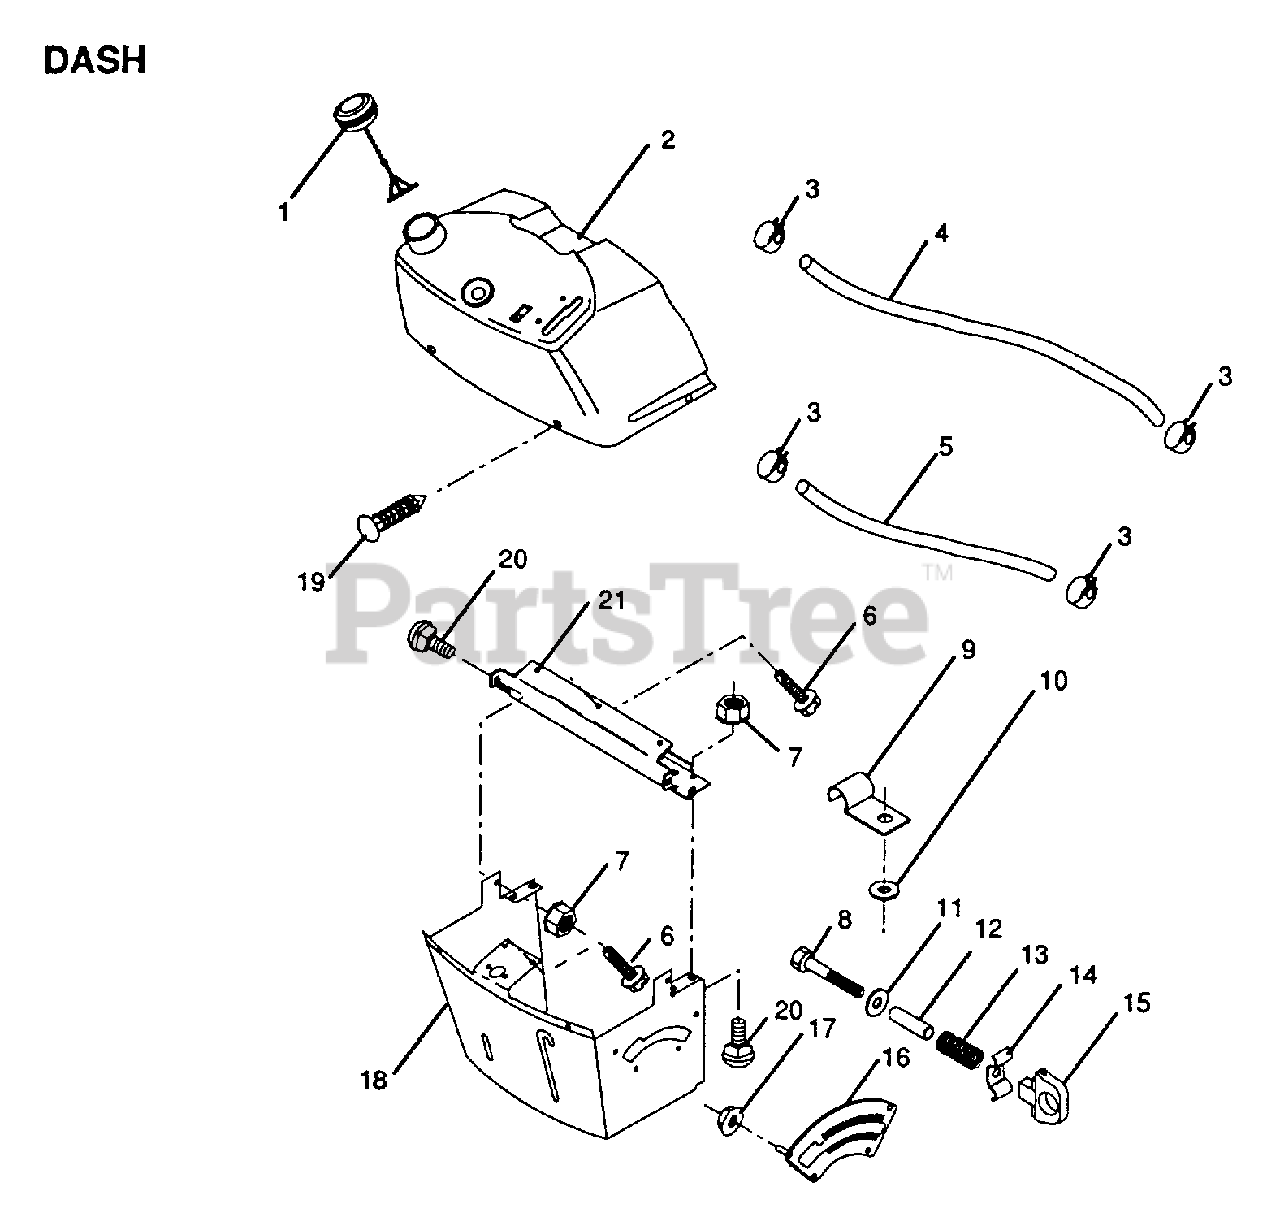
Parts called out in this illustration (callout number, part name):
3	HOSE CLAMP
4	FUEL LINE T
6	SCREW
7	NUT
8	BOLT
9	CLIP T
10	WASHER PM
11	WASHER
12	SPACER SPLIT
13	SPRING T
14	HEIGHT ADJ
15	KNOB
16	ADJUSTER QUAD
17	NUT
18	SUPPORT DASH
19	SNAP
20	BOLT
21	"BRAKE,CROSS"
